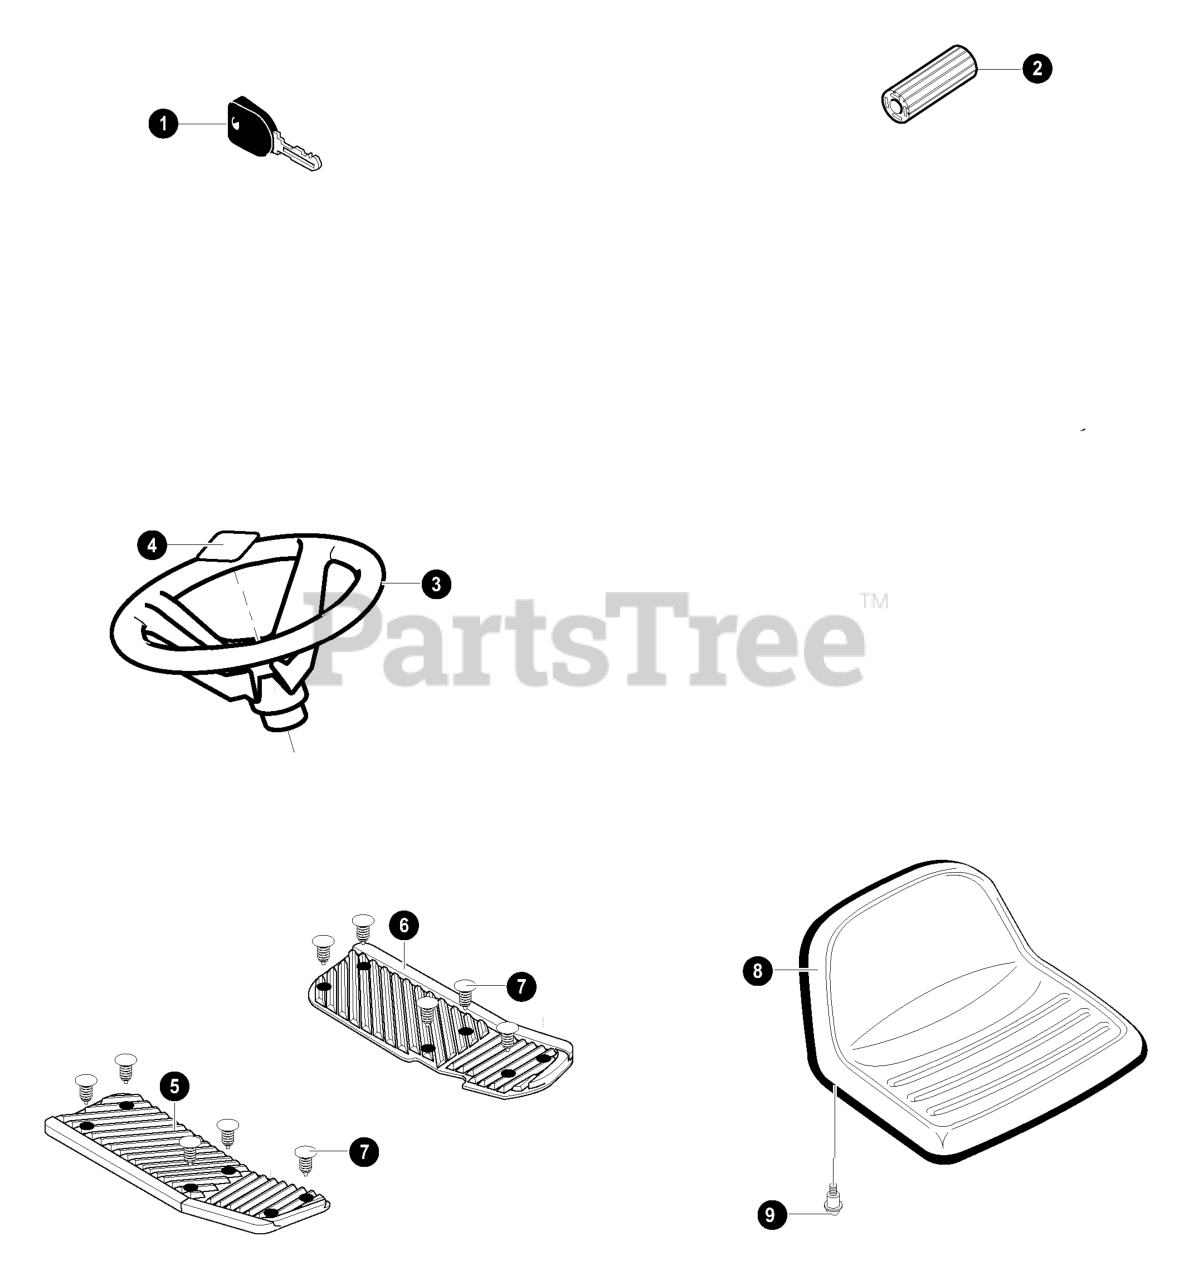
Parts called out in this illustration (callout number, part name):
1	IGNITION KEY
2	COVER PEDAL BRAKE/CLUTCH
3	STEERING WHEEL
4	INSERT 4-SPOKE
5	FOOTREST PAD RH
6	FOOTREST PAD LH
7	FASTENER, RATCHET
9	BOLT, .375X.255 HHSH 5/16-18
